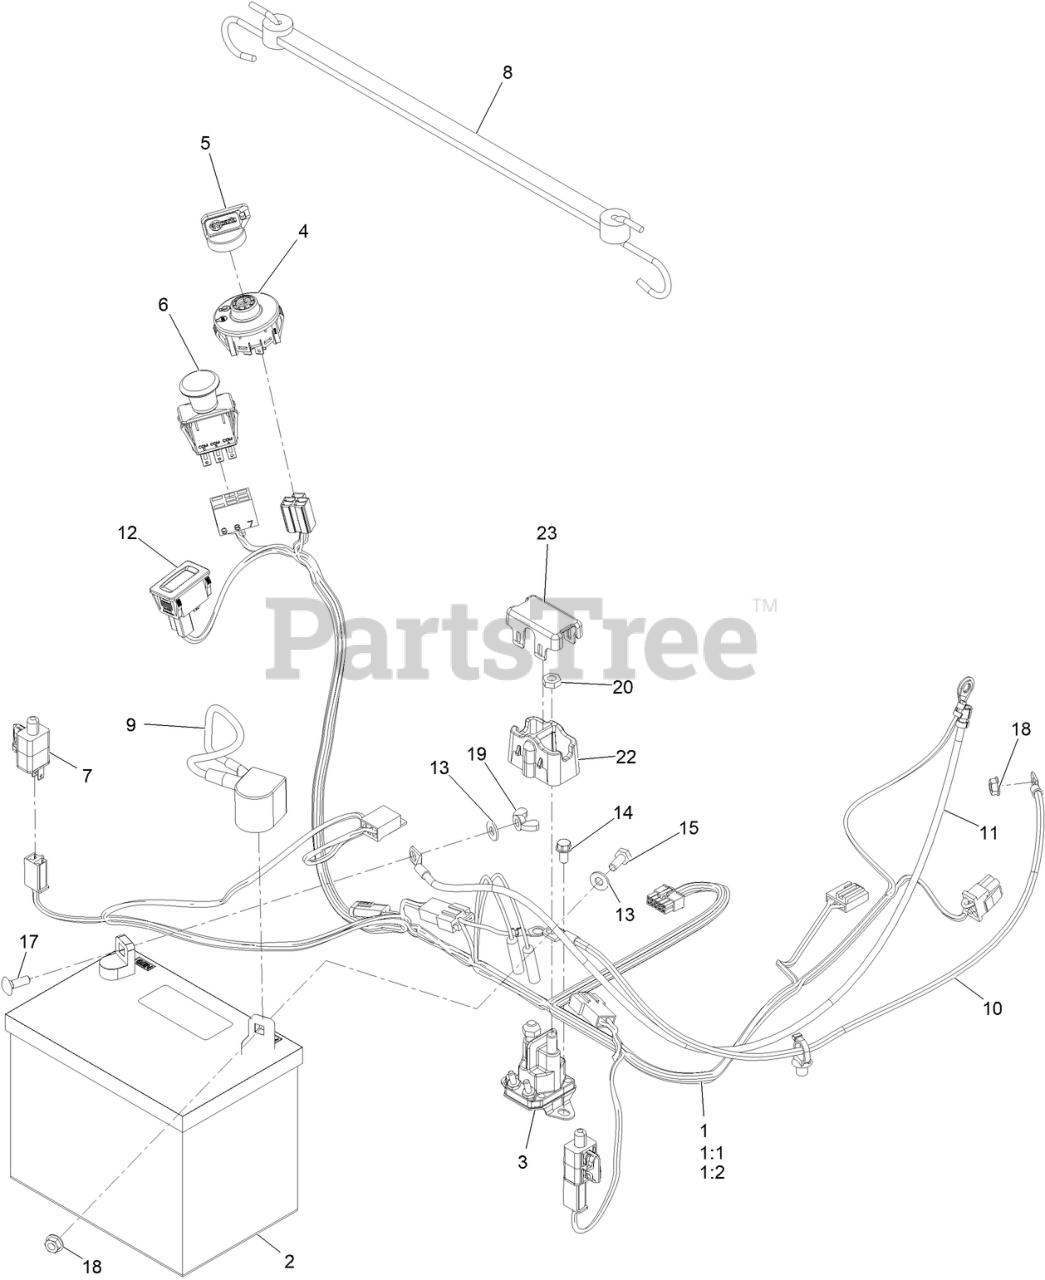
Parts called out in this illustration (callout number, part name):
1	HARNESS-WIRE
2	BATTERY
3	SOLENOID
4	SWITCH-IGNITION
5	KEY-IGNITION
6	SWITCH-PTO
8	STRAP-RUBBER
9	CABLE-BATTERY, POS
10	CABLE-BATTERY, RED (8 GAUGE)
11	CABLE-BATTERY, BLACK
12	HOURMETER
13	WASHER-FLAT
14	SCREW-HWH
15	SCREW-HH
17	BOLT-CARR
19	NUT-WING
20	NUT-JAM
22	COVER-SOLENOID
23	CAP-SOLENOID
